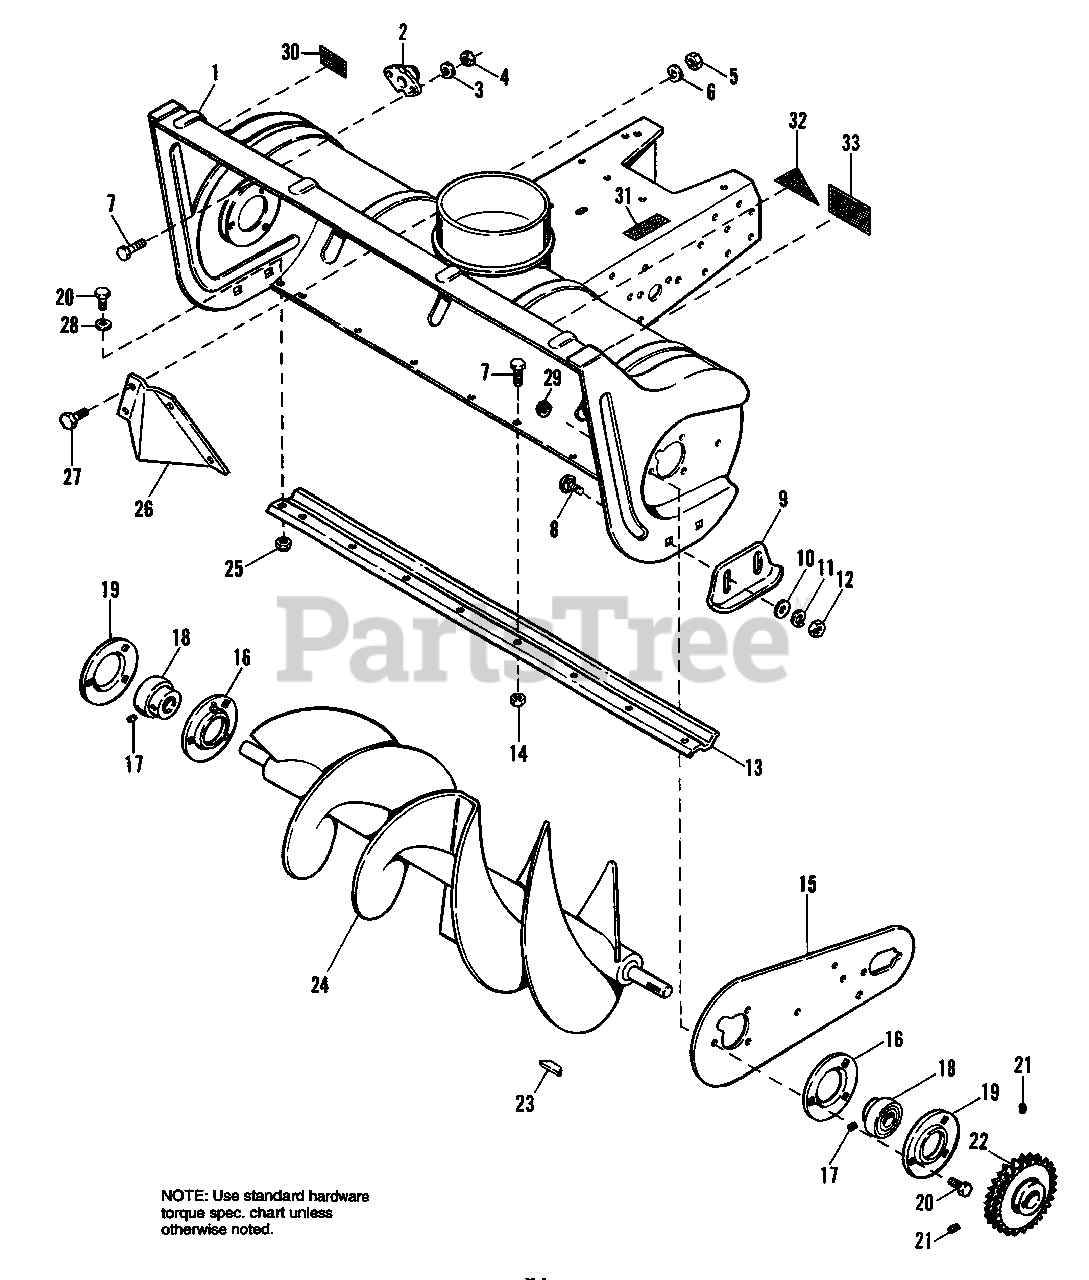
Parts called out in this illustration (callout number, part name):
1	BODY & FRAME ASSY.
2	BEARING, Body Mounted
3	LOCKWASHER, 1/4 Std.
4	NUT, Hex, 1/4-20
5	NUT, Hex, 5/16-18
6	LOCKWASHER, Hex Hd., 1/4-20 x 5/8
7	CAPSCREW, Hex Hd., 1/4-20 x 5/8
8	BOLT, Carriage, 3/8-16 x 5/8
10	WASHER, 3/8 Std.
11	WASHER, 3/8
12	NUT, Hex, 3/8-16
13	SCRAPER BAR
14	NUT, Hex, Lock, 1/4-20
15	RATE, Side
16	FLANGE, Bearing
17	SETSCREW, Hex Hd., 1/4-28 x 1/2
18	BEARING, Cartridge
19	FLANGE, Bearing
20	CAPSCREW, Hex Hd., 5/16-18 X 3/4
21	SETSCREW, 5/16-18
22	DOUBLE SPROCKET ASSY., 29 Teeth
24	ROTOR ASSY.
25	NUT, Hex, Lock, 5/16-18
27	CAPSCREW, Hex Hd., 5/16-18 x 50
28	WASHER, 1/4 Std.
29	NUT, Flangelock, 2 way, 5/16-18
30	DECAL, Caution
31	DECAL, I.D. Plate
32	DECAL, OPEI
33	Danger, Auger
